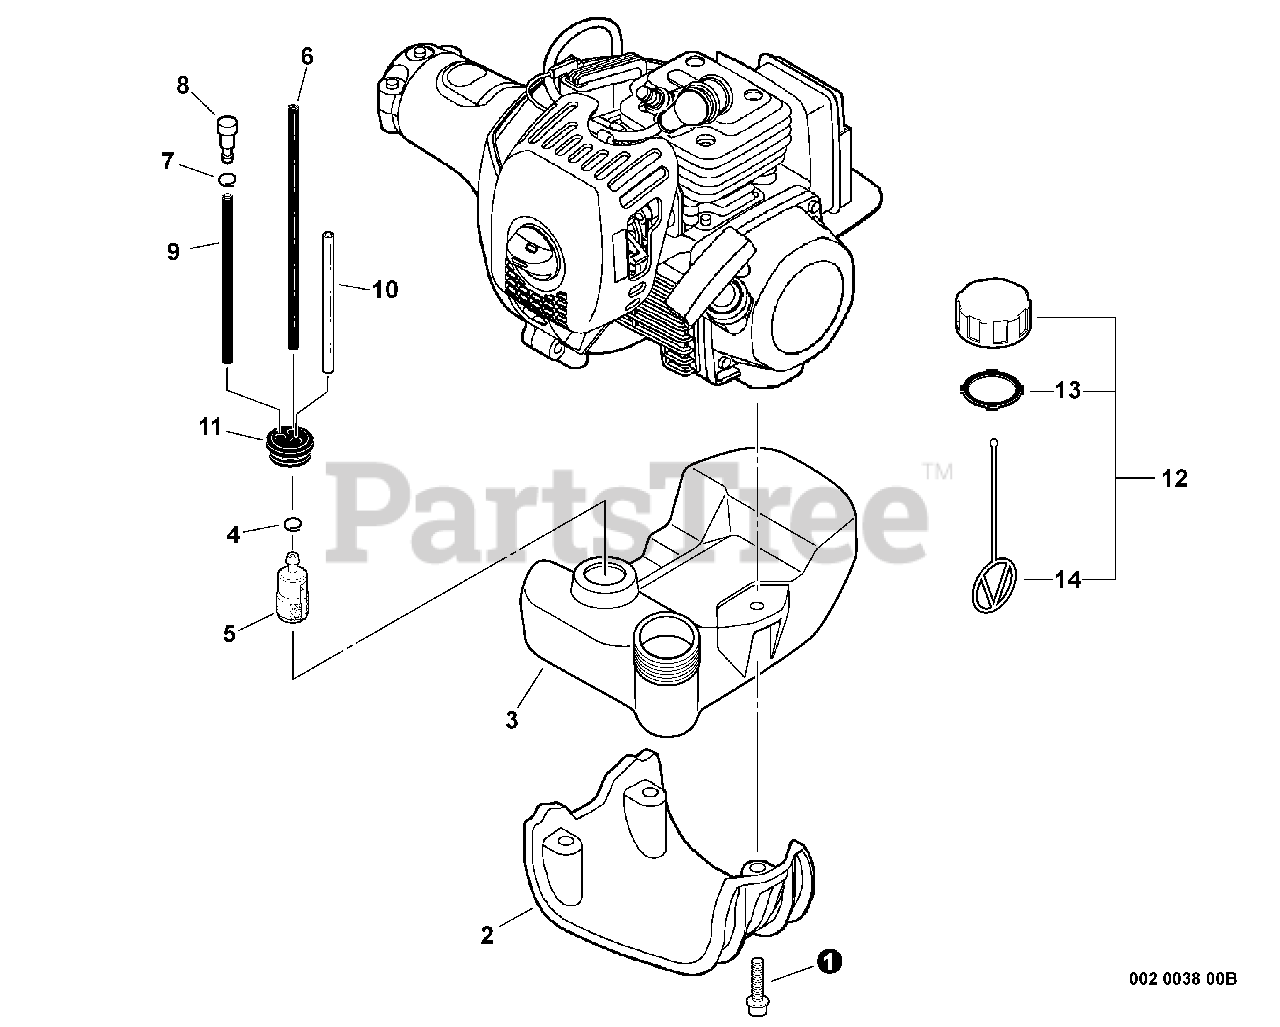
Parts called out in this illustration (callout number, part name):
1	SCREW - 5X20
2	GUARD, FUEL TANK
3	TANK, FUEL
4	CLIP - 6
5	FILTER, FUEL
6	PIPE - 3X5X195 -- BLACK
7	CLIP - 6.5
8	VENT, FUEL TANK
9	PIPE - 3X6X115 -- BLACK
10	PIPE - 3X6X80 -- CLEAR
11	GROMMET
12	CAP ASSY - ORANGE
13	GASKET, CAP
14	CONNECTOR, CAP
